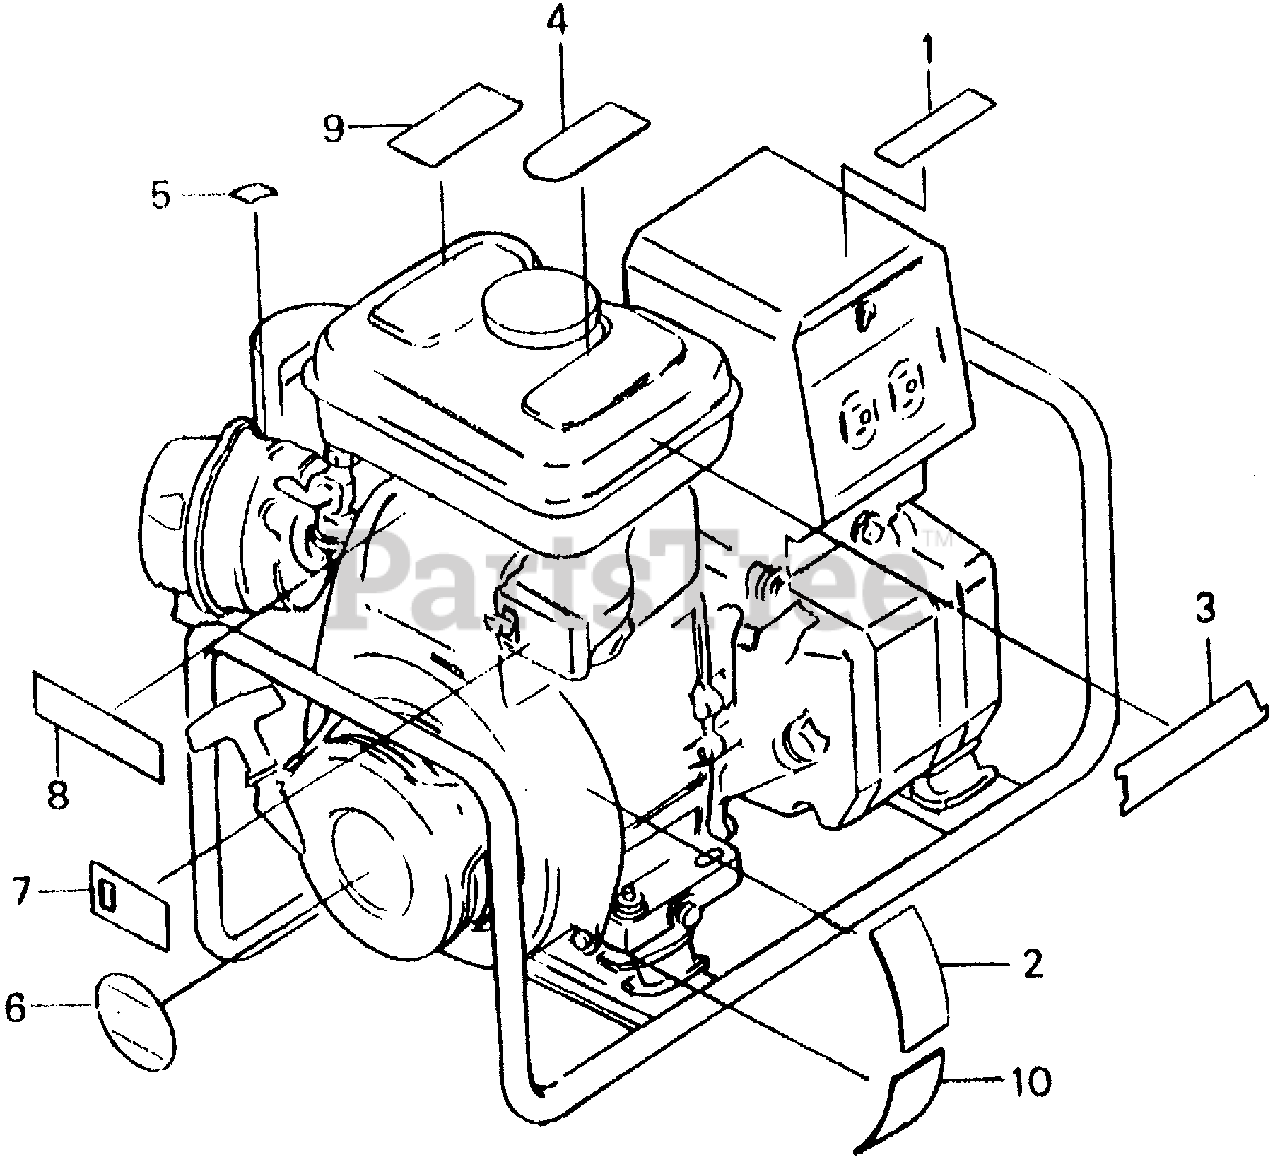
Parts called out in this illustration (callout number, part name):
2	PLATE, CAUTION (EG2200Z)
3	EMBLEM, FUEL TANK (NOT AVAILABLE)
4	MARK, CAUTION (ENGLISH/FRENCH)(SPANISH)
5	MARK, CHOKE
6	LABEL, OIL ALERT
7	MARK, OIL ALERT UNIT SWITCH
8	LABEL, CAUTION
9	MARK, CAUTION (CO)(ENGLISH/FRENCH)(SPANISH)
10	MARK, OIL CAUTION
